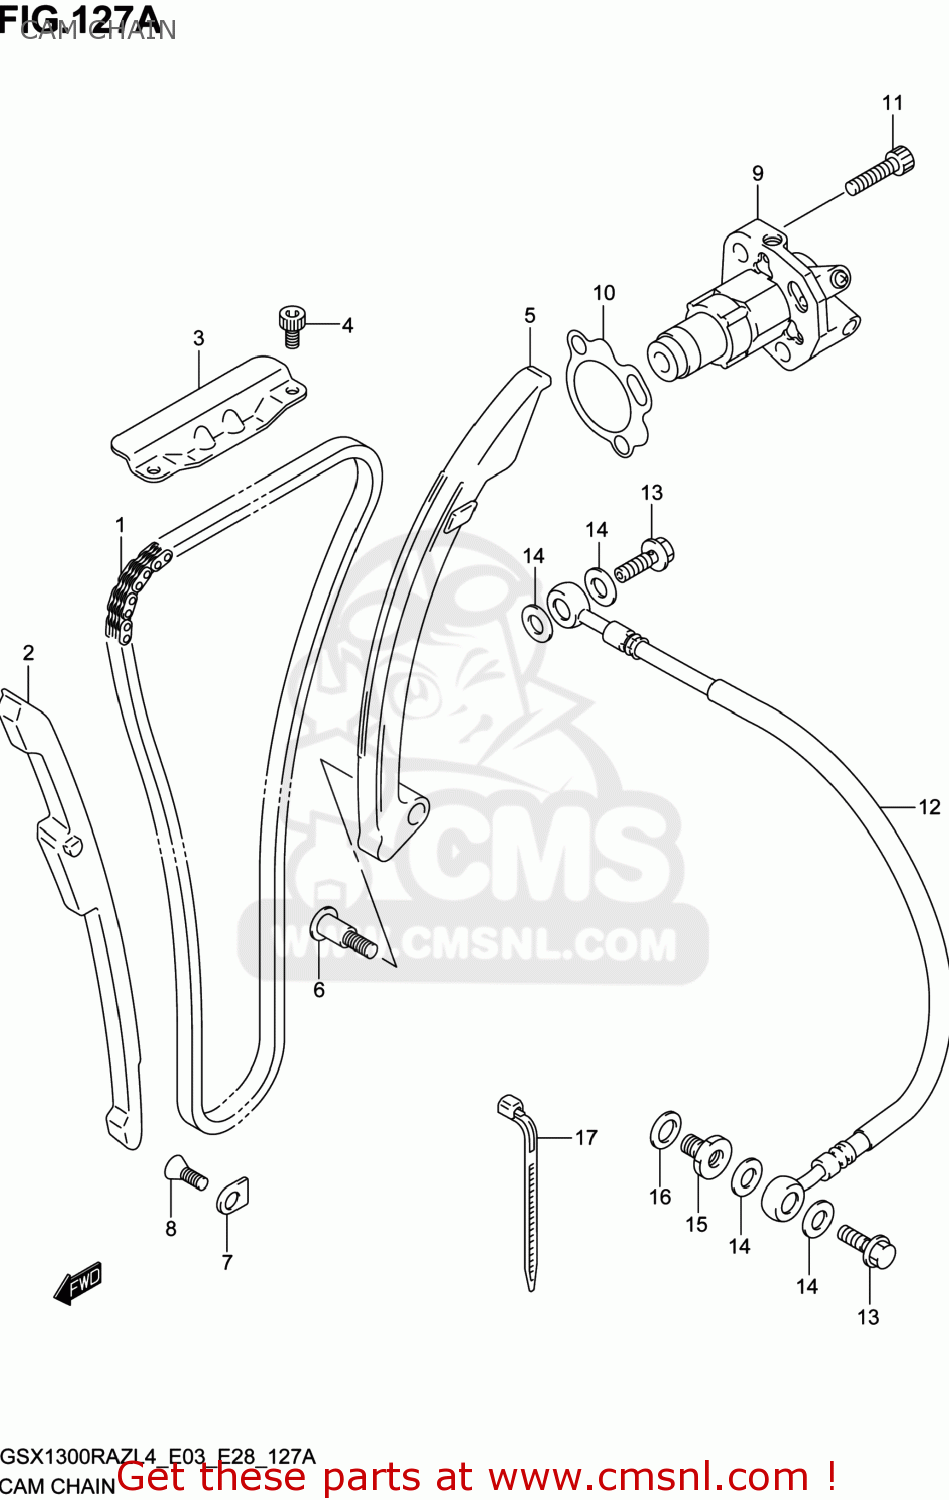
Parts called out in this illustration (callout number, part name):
1	CHAIN,CAMSHAFT DRIVE
2	GUIDE,CAM CHAIN NO.1
3	GUIDE,CAM CHAIN NO.2
4	BOLT
5	TENSIONER,CAM CHAIN
6	BOLT,CAM CHAIN TENSIONER
7	RETAINER,CAM CHAIN GUIDE NO.1
8	SCREW
9	ADJUSTER ASSY,TENSIONER
10	GASKET,TENSIONER ADJUSTER (NAS)
11	BOLT
12	HOSE,CAM CHAIN TNSN ADJ OIL
13	BOLT,ADJ OIL HOSE UNION
14	GASKET(7.8X13.5X1.2) (NAS)
15	PLUG,ADJ OIL HOSE UNION
16	GASKET(13.8X18.8X4.8) (NAS)
17	CLAMP(L:165)
